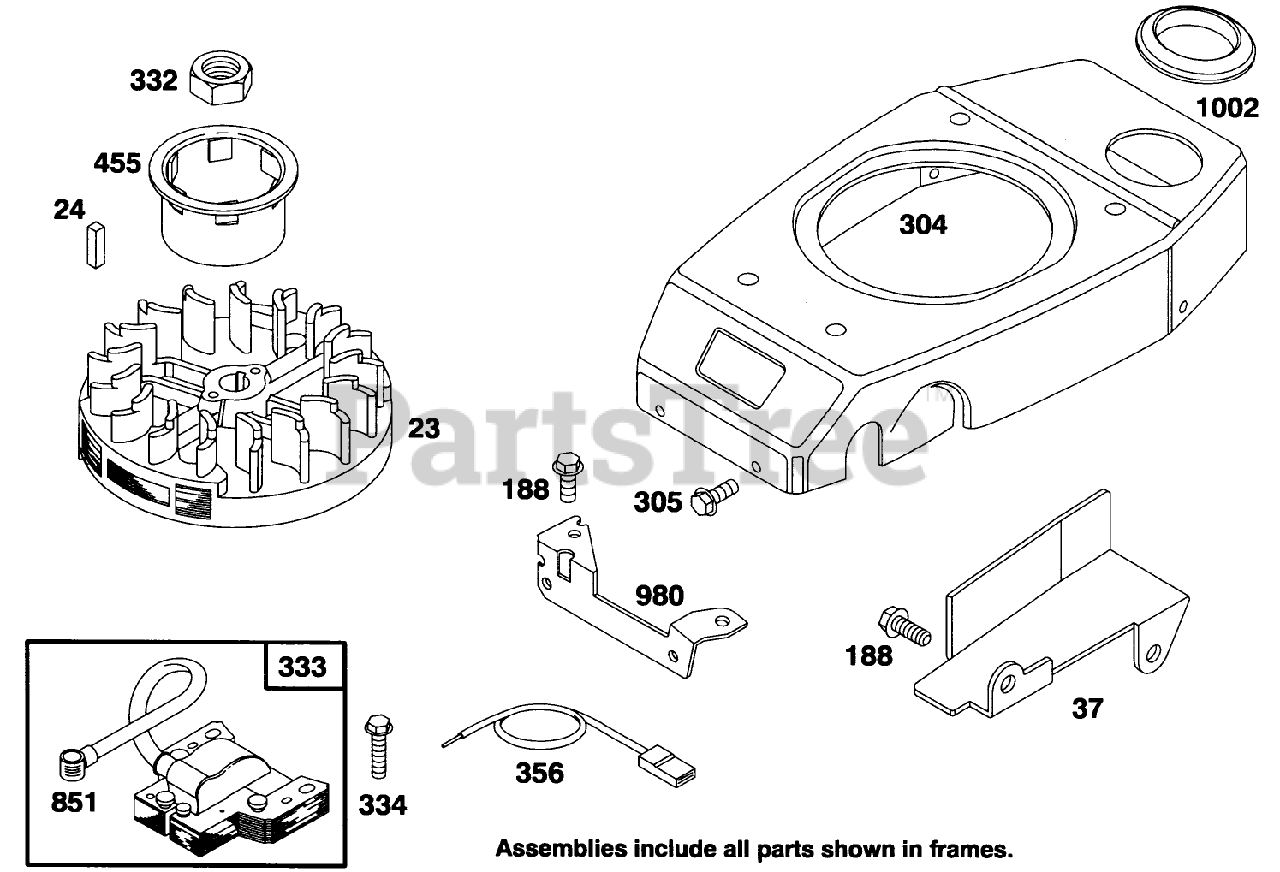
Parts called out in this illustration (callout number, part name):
24	KEY - FLYWHEEL
37	GUARD - FLYWHEEL
188	SCREW - SEM
304	HOUSING - BLOWER
305	SCREW - HEX HEAD
332	NUT - HEXAGON
356	WIRE - GROUND
980	BRACKET-BLOWER HSG
